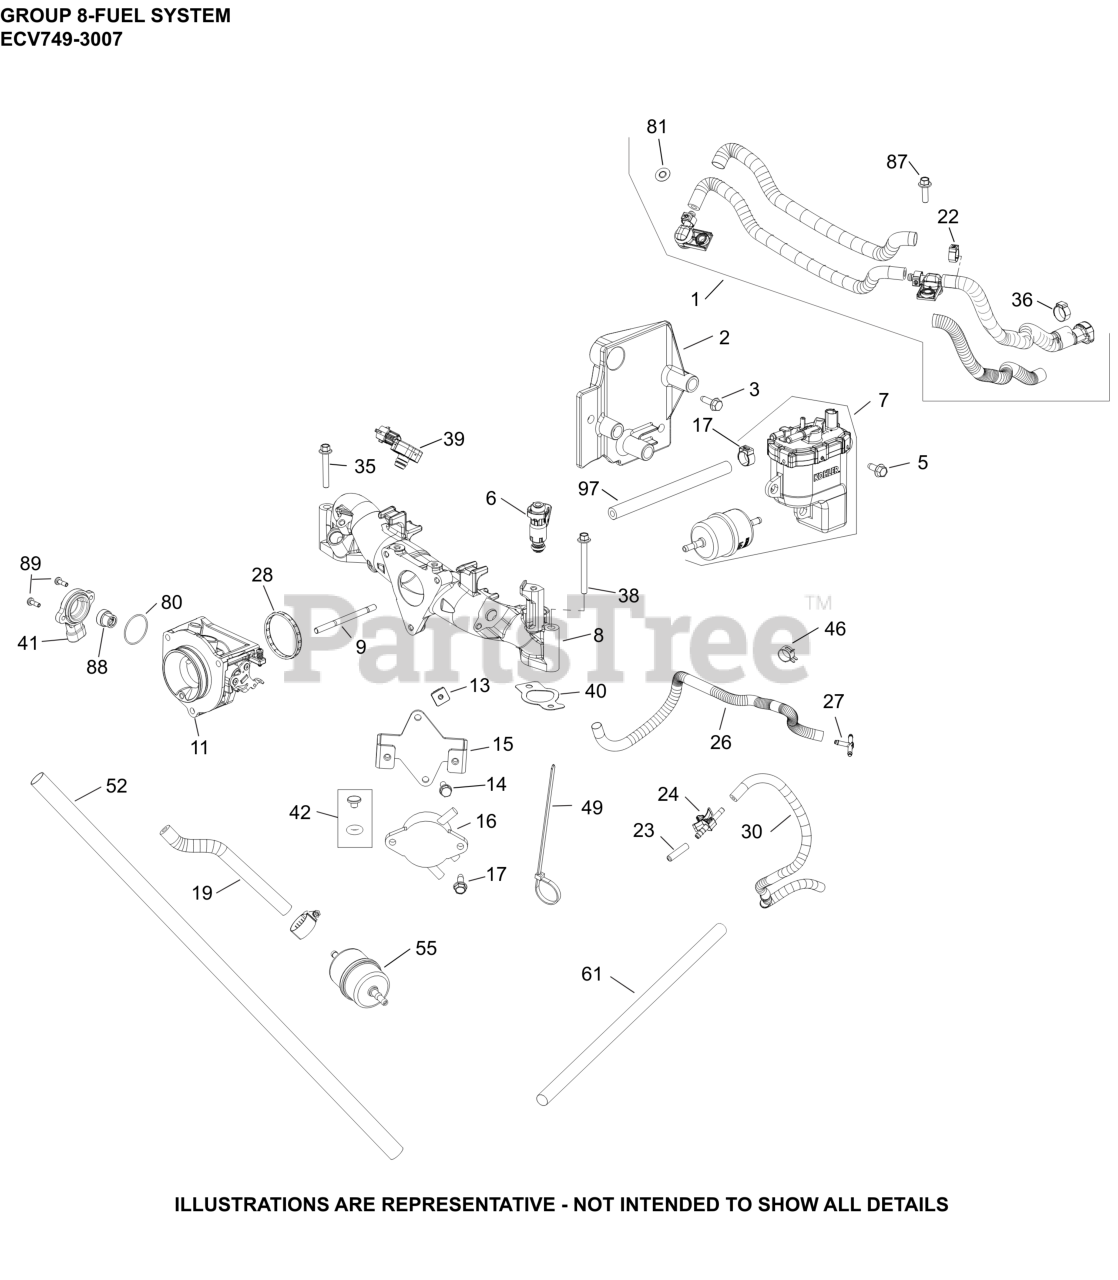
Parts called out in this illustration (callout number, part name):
1	FUEL HOSE ASSY(ECV,FCV,EZT,EKT,PCH,PCV)
2	KIT,BAFFLE, FUEL MODULE
3	SCREW, THREAD FORMING
5	SCREW, FLG M6X1.0X16
6	INJECTOR, FUEL
7	KIT, FUEL PUMP MODULE
8	KIT, MANIFOLD
9	STUD,M6X1.0X84
11	BODY, THROTTLE ASM (30)
13	NUT, PLASTIC - BLACK
14	SCREW, HEX HEAD
15	BRACKET, FUEL PUMP MOUNTING
16	PUMP, FUEL
17	SCREW, THREAD FORMING
19	HOSE,LW PERM.FUEL 24.00"-USE 25 111 81-S
22	CLAMP, OETIKER
23	CAP, MASKING
24	CONNECTOR, EVAPORATIVE
26	SLEEVE, ANTI-ABRASION
27	TEE CONNECTOR
28	O-RING, THROTTLE BODY
30	HOSE, EVAPORATIVE (15.0)
35	SCREW, FLG M6X1.0X40
36	CLAMP, HOSE
38	SCREW, FLG M6X1.0X60
39	SENSOR, T-MAP
40	KIT, INTAKE MANIFOLD GASKET
41	SENSOR, THROTTLE POSITION
42	KIT, FUEL INJECTOR O-RING
46	SPRING CLAMP, HOSE
52	SLEEVE, HEAT REFLECTIVE
55	FILTER, FUEL
61	SLEEVE, ANTI ABRASION -USE 25 431 12-S
80	O-RING, TPS SENSOR
81	CLIP, RETAINER
87	SCREW, FLG M6x1.0x20
88	MAGNET ASSEMBLY, TPS
97	HOSE, FUEL LOW-PERMEATION
NI	SLEEVE, ANTI ABRASION-USE 25 431 12-S
